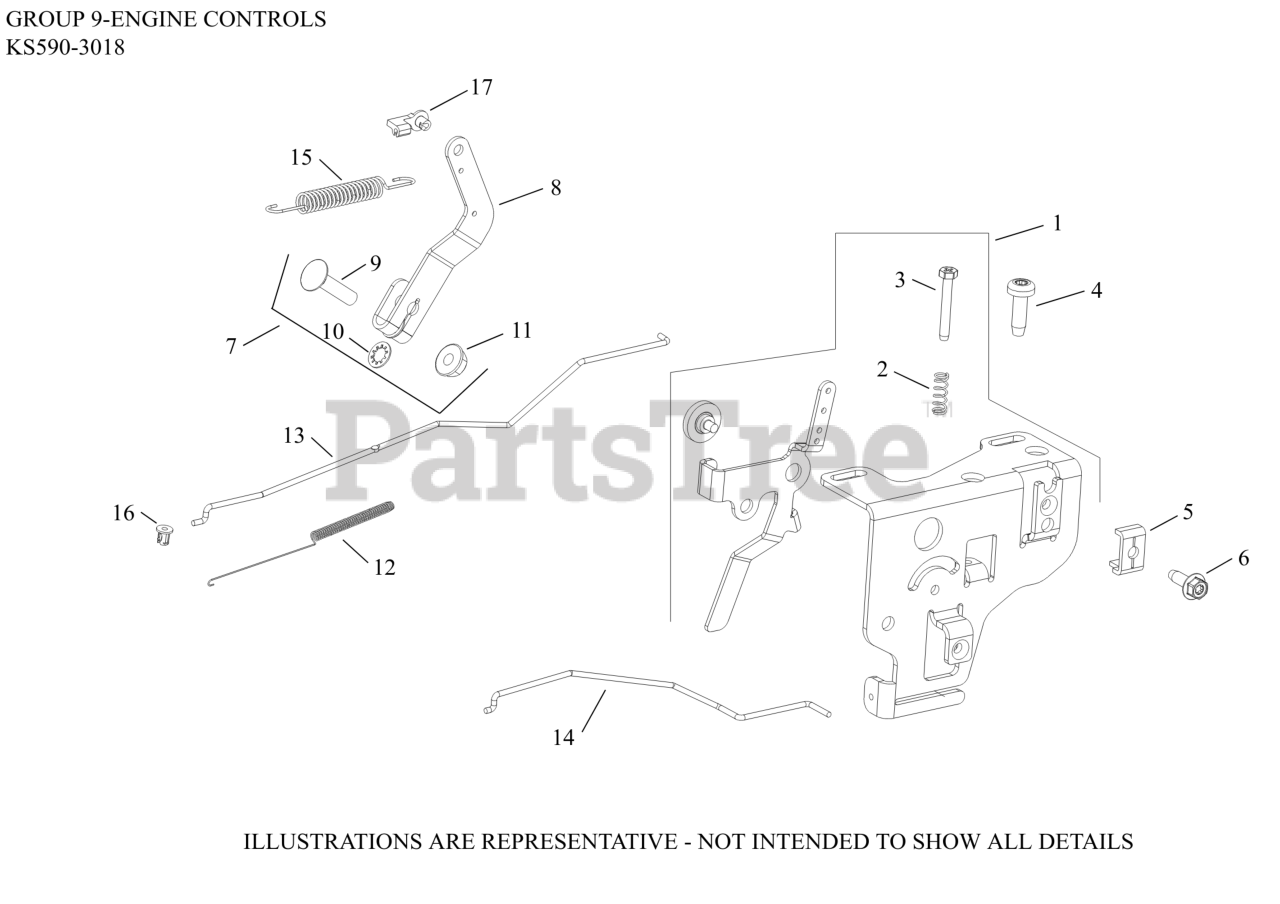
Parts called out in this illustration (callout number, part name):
1	CONTROL ASSY SPEED
2	SPRING, SPEED CONTROL
3	KIT, IDLE ADJ SCREW & SPRING
4	SCREW, THREAD FORMING
5	CLAMP, CABLE-(#2523753S)
6	SCREW, THREAD FORMING
7	LEVER, GOVERNOR ASSY
8	LEVER, GOVERNOR
9	BOLT, RD HD SQ NCK 1/4-20X1"
10	WASHER, INT TOOTH LOCK 1/4"
11	NUT, FLANGE 1/4-20
12	SPRING, LINKAGE
13	LINKAGE, THROTTLE
14	LINKAGE, CHOKE
16	BUSHING, LINKAGE RETAINING
17	BUSHING, THROTTLE LINKAGE
NI	SPRING, GOVERNOR
